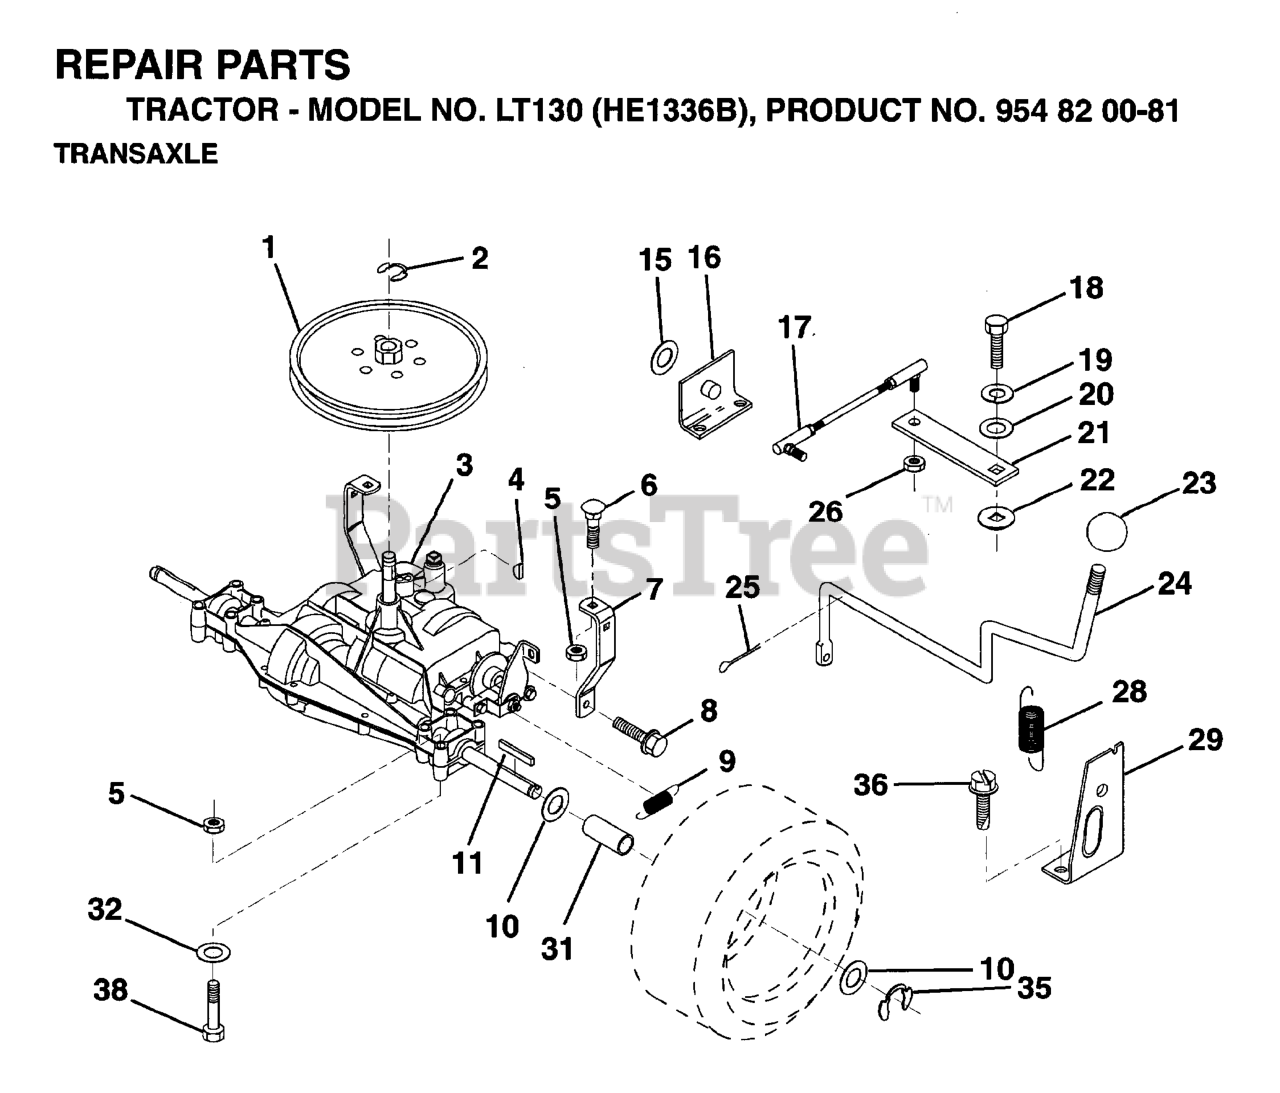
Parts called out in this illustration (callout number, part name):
2	RETAINING RING LT
4	KEY STD (1373) DANA
5	LOCKNUT
6	RP BOLT 5/16-18 X3/4 ZN/YEL GR
7	STRAP,TORQUE
8	SCREW.THDROL.5/16-18X3/4.TTY
9	SPRING,BRAKE RETURN
11	SQUARE KEY
15	WASHER
16	SUPT, HDLE SHT LH
18	BOLT 1/4-28X3/4
19	LOCKWASHER
22	WASH-SHFT PLT LT
23	KNOB.DUCKHEAD.1/2
24	ROD, SHIFT
25	PIN COTTER
26	LOCKNUT
28	SPRING.EXTENSION
29	SUPPORT HANDLE SHAFT RH
31	SPACER AXLE
32	WASHER
36	SCREW
38	BOLT HEX 5/16-18 GR 5
